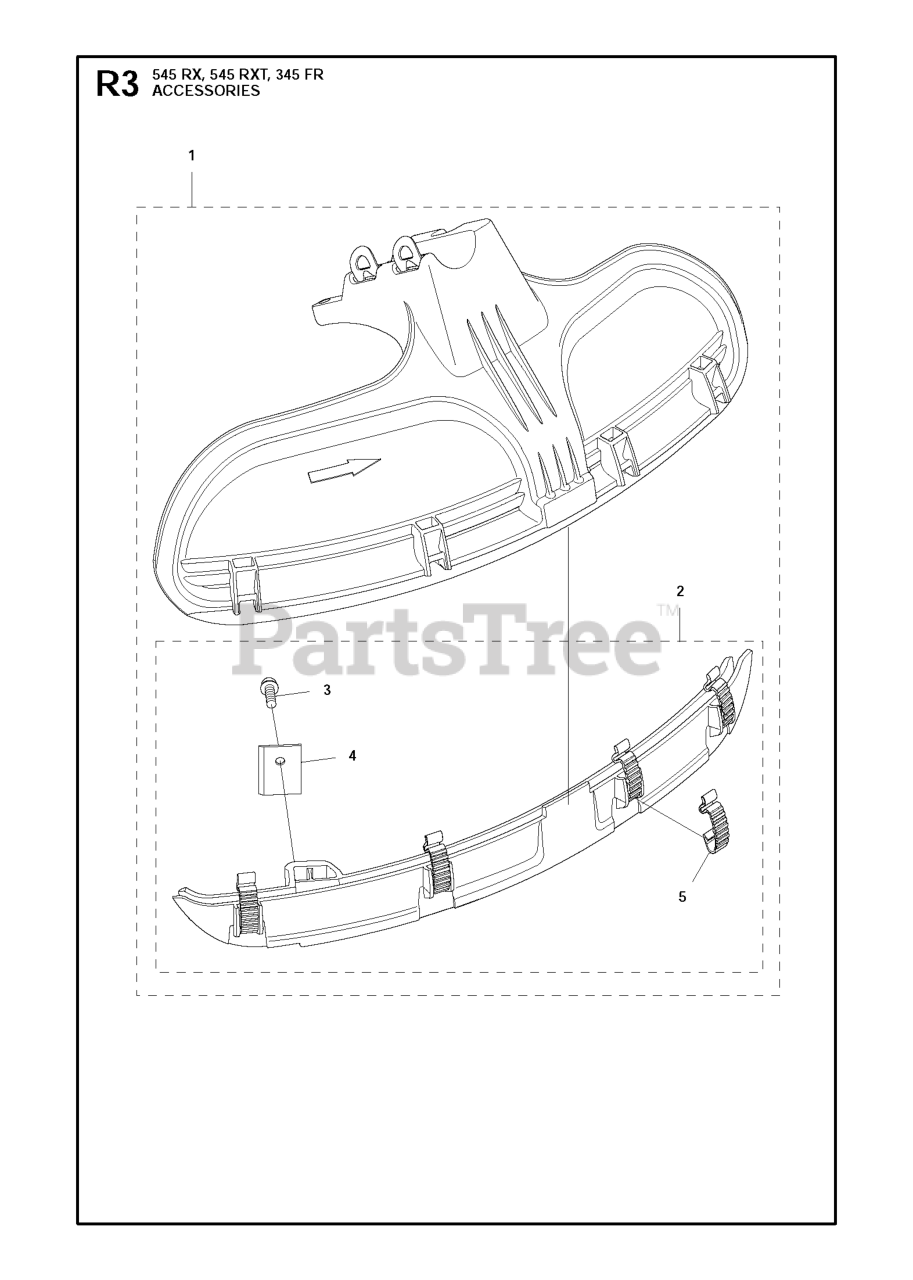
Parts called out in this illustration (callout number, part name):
1	COMBINATION GUARD
2	SPLASH GUARD
3	SCREW IHSCFT
4	LINE CUTTER
